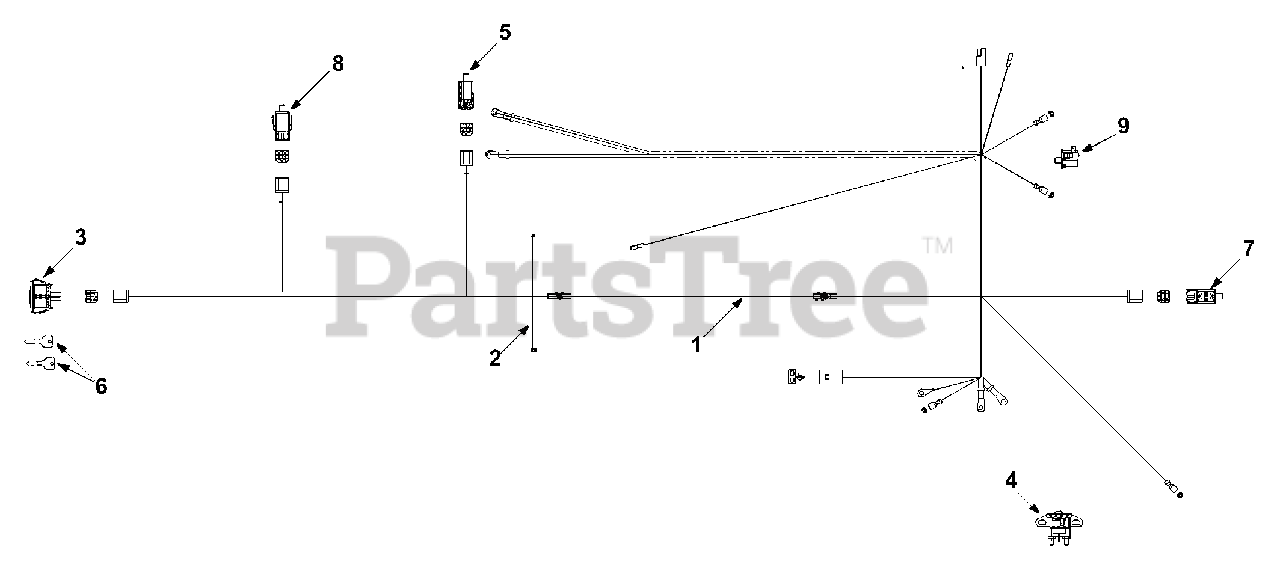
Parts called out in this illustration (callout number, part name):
1	Harness Assembly
2	Cable Tie
3	Key Switch
4	Solenoid: 12 V. 100 amp.
5	Interlock Switch
6	Key
7	Switch: Plgr N.C./N.C.
8	Switch: Plgr N.O./N.C.
9	Switch: Mt. Snap N.C.
